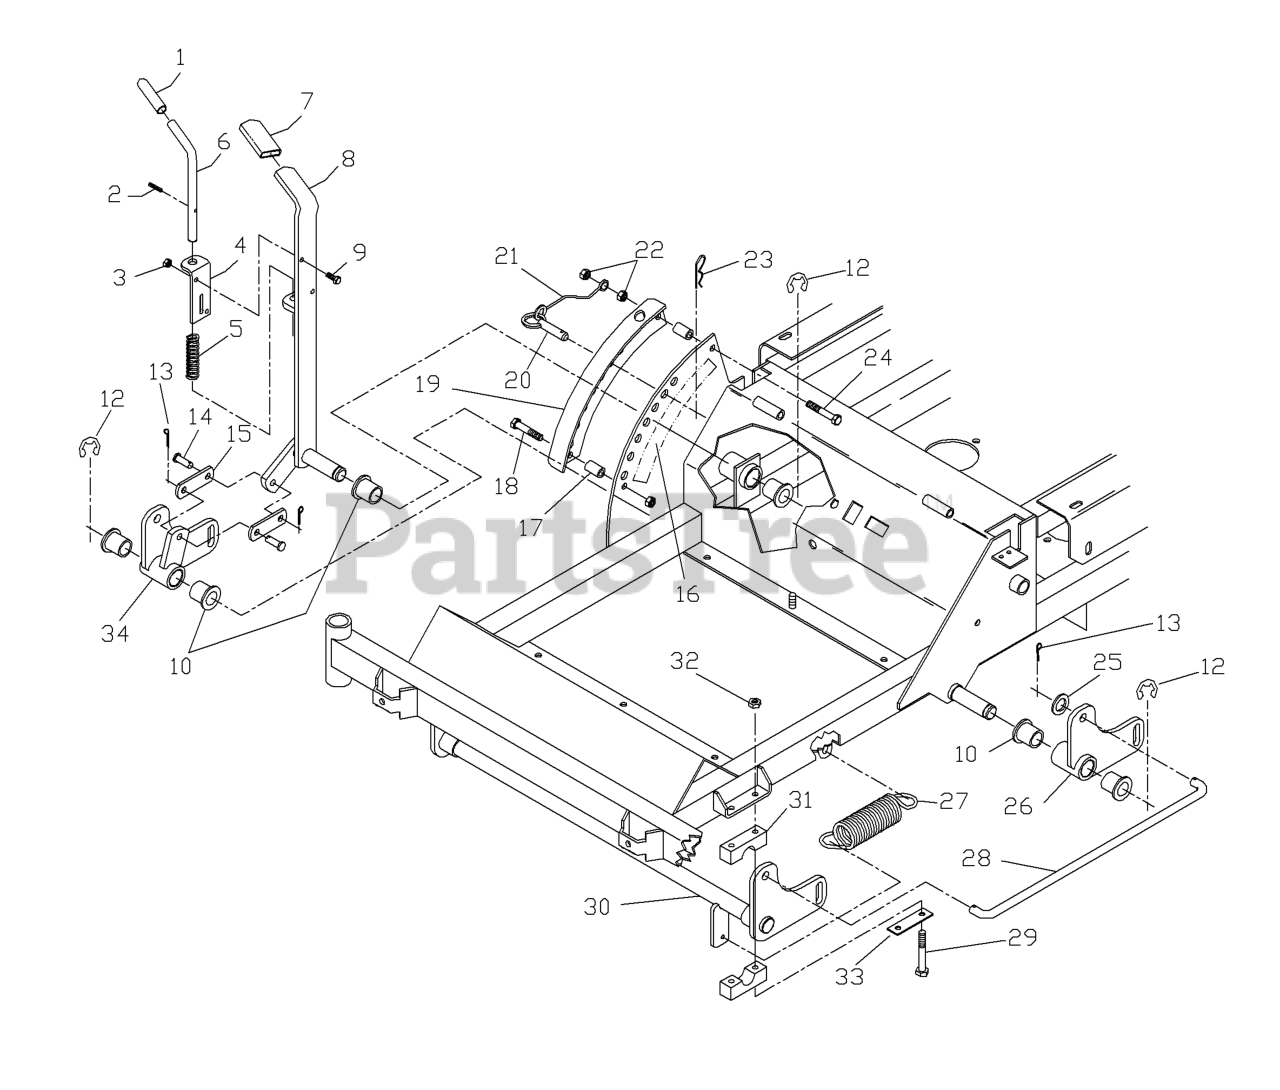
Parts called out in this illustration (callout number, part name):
2	ROLL PIN 3/16 X 1-1/4 ZD
3	NUT 1/4C CENTER LOCK
4	PIN MT, UPPER
8	LEVER WELDMENT
9	HCS 1/4C X 3/4 HCS
10	BUSHING, FLANGED
11	BELLCRANK WLDMT - RT
12	E-RING 7/8
13	RP_COTTER PIN 1/8 X 3/4
14	CLEVIS PIN 3/8 X 1 1/8
16	DECAL, LOCATOR
18	HCS 3/8C X 2
19	LOCATOR WELDMENT
22	NUT 3/8C CENTERBLOCK
23	HAIRPIN #4
24	HCS 3/8C X 2 1/4
25	BUSHING 1/2 MACH
26	BELLCRANK WLDMT-LT
29	HCS 5/16C X 2-3/4
30	LIFT WLDMT
31	PILLOW BLOCK
32	NUT 5/16C CENTERLOCK
33	REINFORCEMENT BAR
34	BELLCRANK WLDMT - RT
